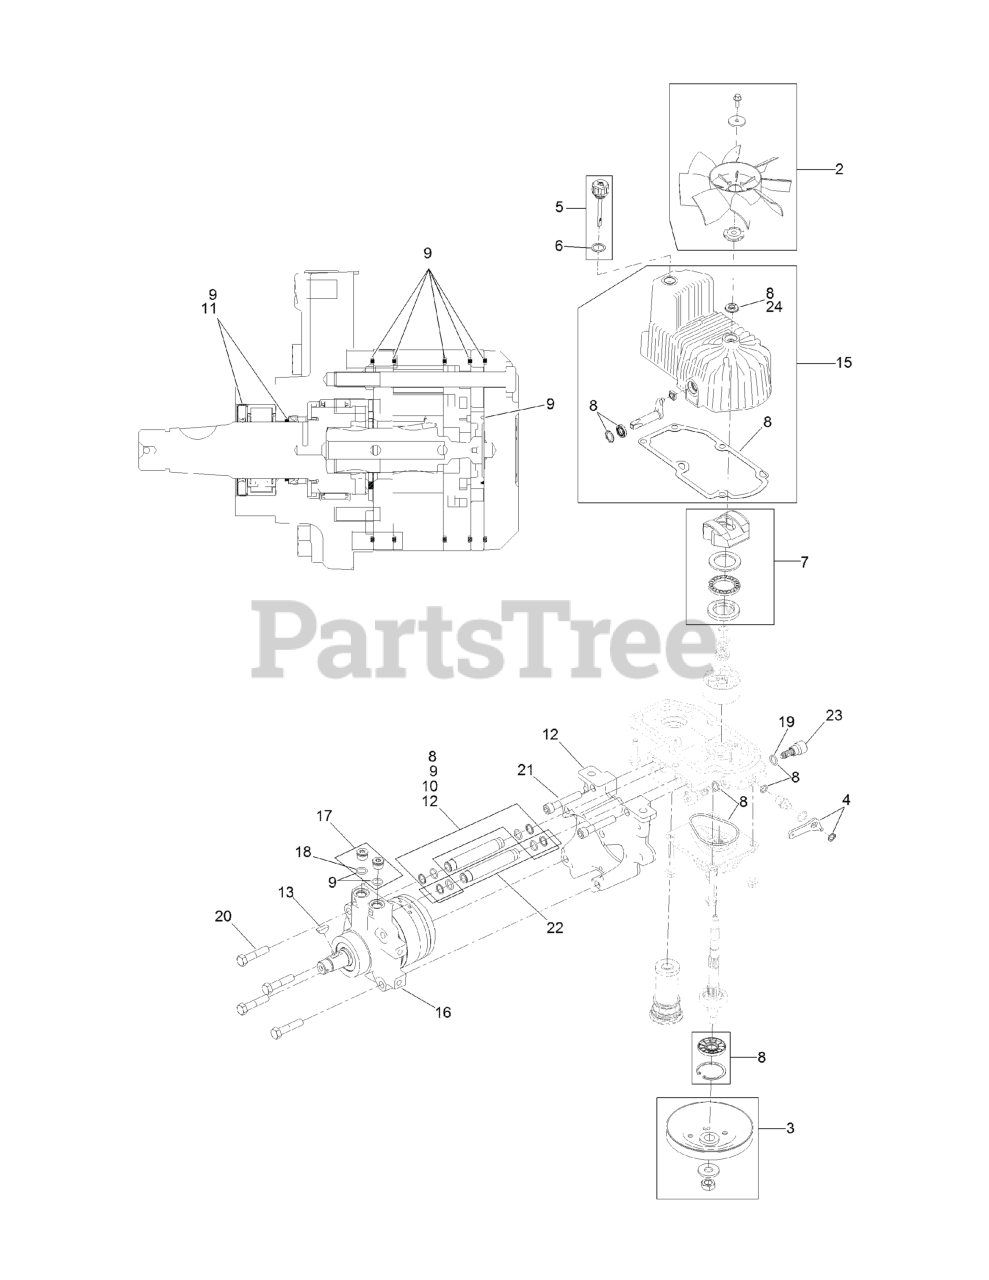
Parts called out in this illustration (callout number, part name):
2	FAN KIT
3	PULLEY KIT
4	HANDLE-BYPASS VALVE, HYDRO
5	DIPSTICK-HYDRO W/GASKET
6	GASKET-DIPSTICK, HYDRO
7	SWASH BLOCK KIT
8	PUMP SEAL KIT
9	MOTOR SEAL KIT
10	TUBE SEAL KIT
11	OUTPUT SHAFT SEAL KIT
12	NOSE CUP-UHT
13	KEY-WOODRUFF
15	HOUSING-HYDRO, LH
16	MOTOR-HYDRAULIC, LH 280CC
17	MAGNETIC PLUGS SERVICE KIT
19	O-RING-CHECK VALVE
20	SCREW HH
21	SCREW-HSH
22	HYDRAULIC TUBE KIT
23	SHOCK VALVE, 16CC HYDRO
24	SEAL-FAN DRIVE
25	16Cc LH Pump Section Kit
26	16Cc LH Rotating Grp Kit
